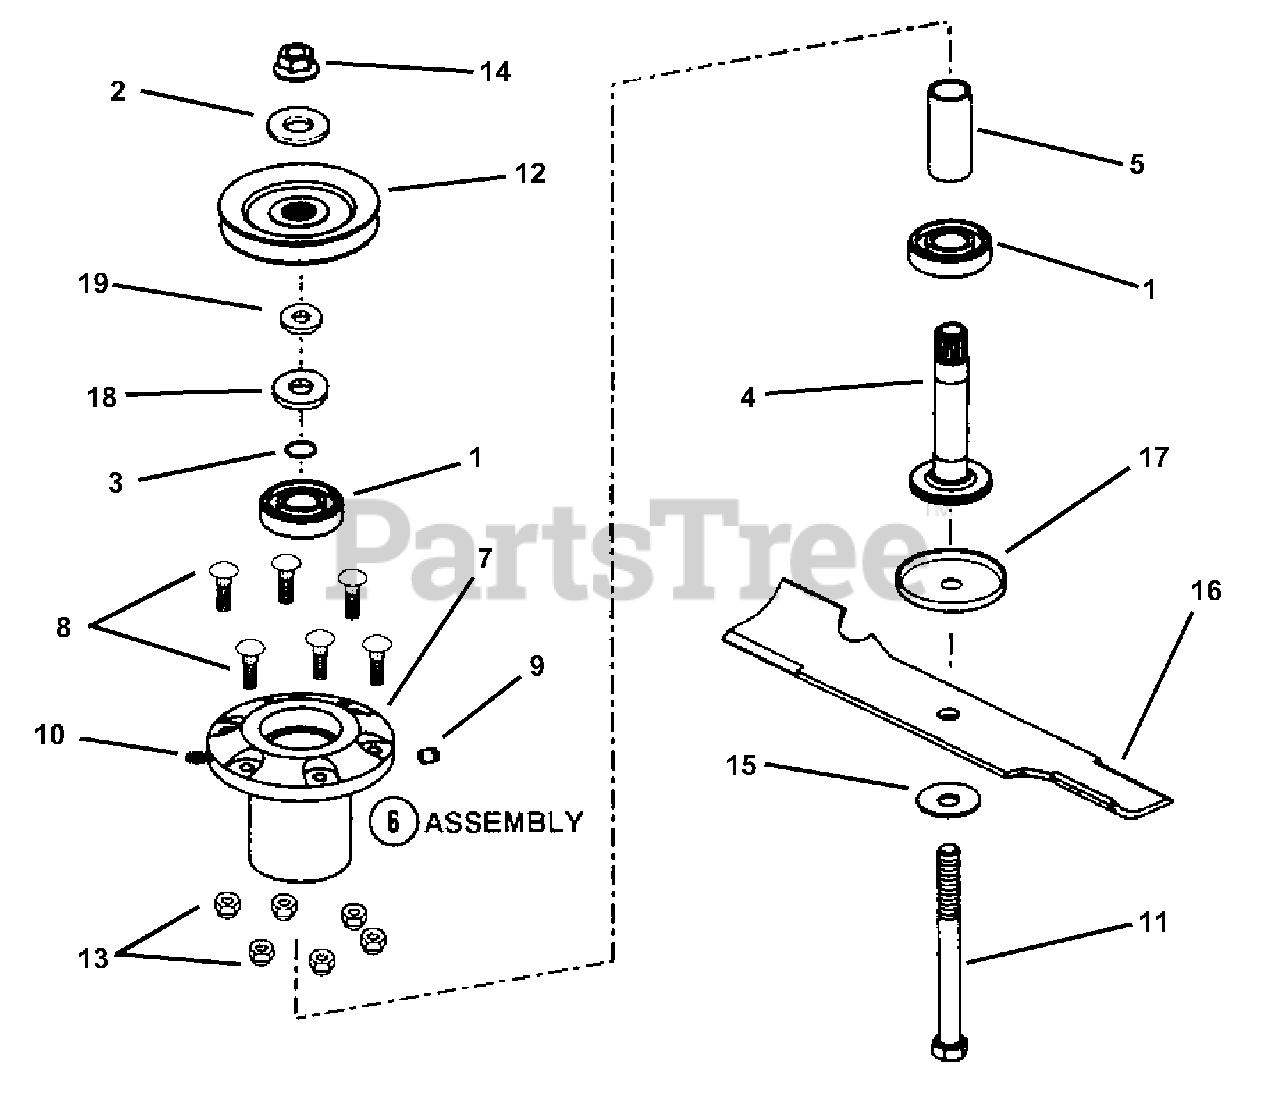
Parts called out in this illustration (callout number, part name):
1	BEARING, Sealed
2	WASHER, 5/8" SAE Flat
3	SNAP-RING, Spindle Shaft
4	ASSEMBLY, Spindle Shaft
5	SPACER, Bearing
6	ASSEMBLY, Casting
7	HOUSING, Spindle
8	BOLT, 3/8-16 x 1-1/4" Rib Necked
9	VENT, Spindle
10	LUBE FITTING, 1/4-28 Thread Forming
11	BOLT, Blade 5/8-11 x 7" Hex Head, Grade 5
12	PULLEY, Driven 4.75" O.D.
13	NUT, 3/8-16 Hex Nyloc
14	NUT, 5/8-11 Hex Flange Lock, Grade 5
15	WASHER, Beveled
16	BLADE, 16-5/16"
17	CUP, Spindle Cover
18	SEAL, Nylos
19	WASHER
